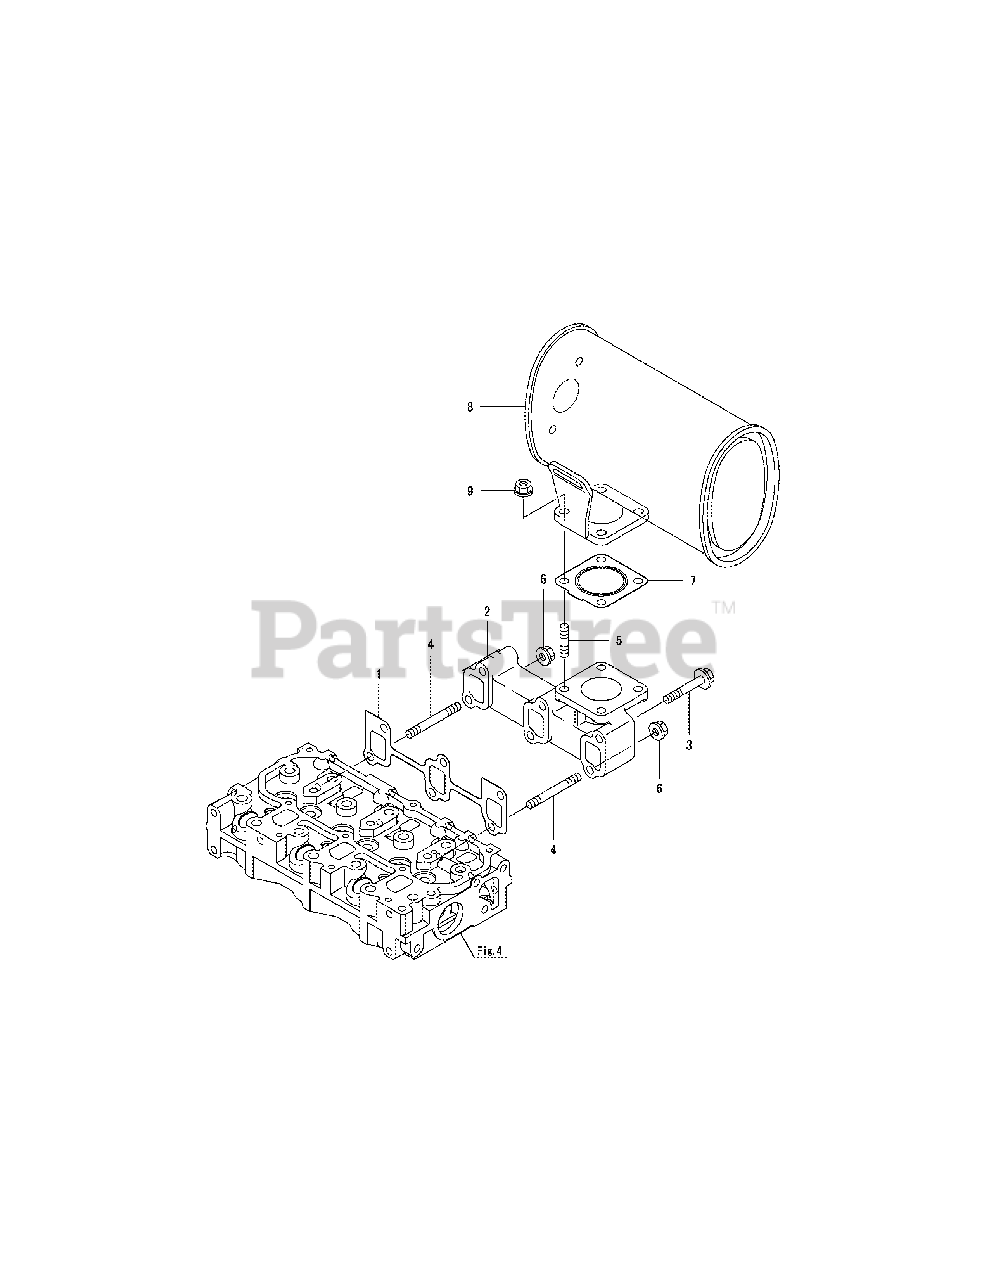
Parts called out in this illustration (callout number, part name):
1	GASKET, MANIFOLD
2	MANIFOLD, EXHAUST
7	GASKET, MUFFLER
